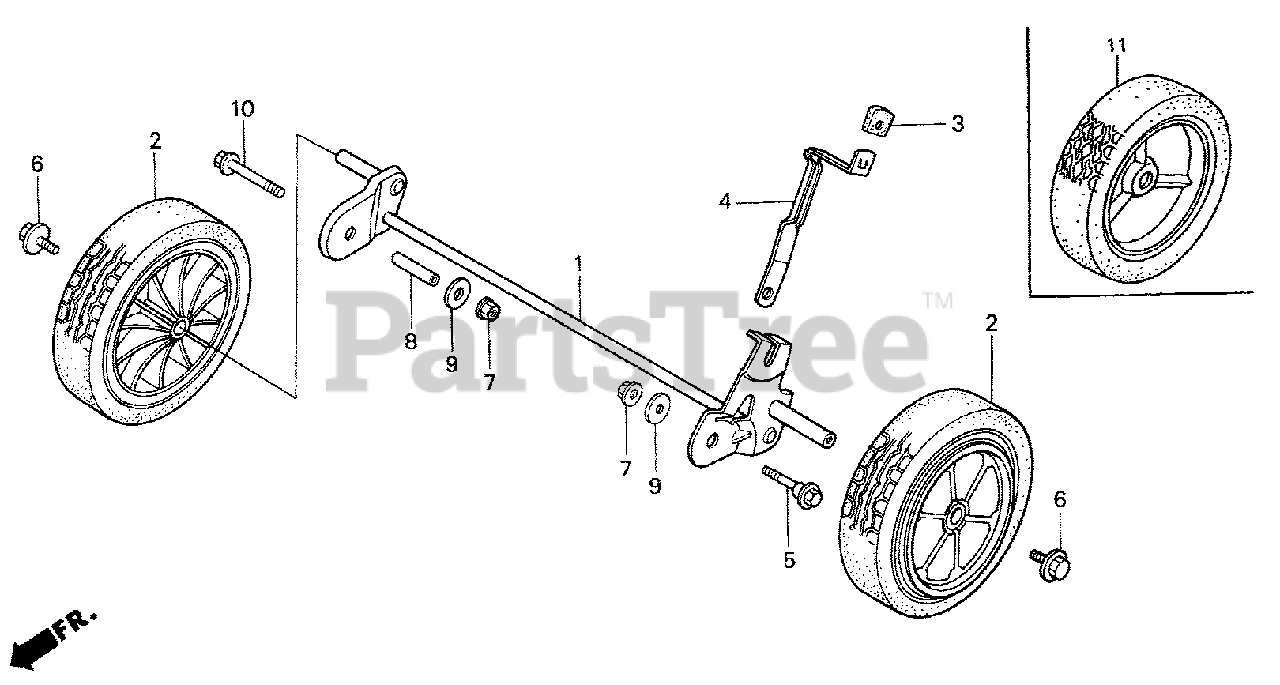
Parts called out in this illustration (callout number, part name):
1	SHAFT, RR. AXLE
2	WHEEL (7X1.5)
2	WHEEL (7") *NH31* (MCKINLEY WHITE)
3	GRIP, ADJUSTER
4	PLATE, RR. ADJUSTING
5	BOLT, ADJUSTING CENTER
6	BOLT, WHEEL
7	NUT, FLANGE (M8X1.25) (SELF-LOCK)
8	COLLAR A, ADJUSTING CENTER
9	WASHER, PLAIN (8MM)
10	BOLT, FLANGE (8X50)
11	WHEEL (7") *NH31* (MCKINLEY WHITE)
